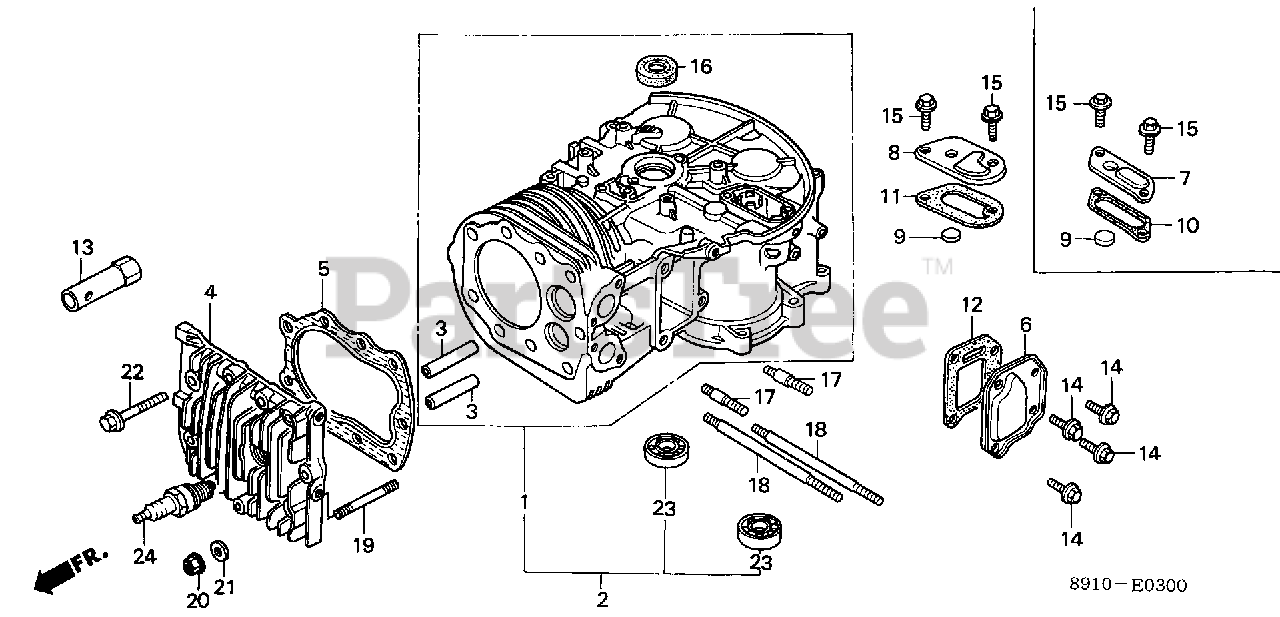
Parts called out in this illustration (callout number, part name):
3	GUIDE, VALVE
4	CYLINDER HEAD
5	GASKET, CYLINDER HEAD
6	COVER, TAPPET ROOM
8	CAP, BREATHER CHAMBER
9	VALVE, BREATHER
11	GASKET, BREATHER CAP
12	GASKET, TAPPET COVER
13	WRENCH, SPARK PLUG (NOT AVAILABLE)
14	BOLT, FLANGE (6X12) (CT200)
15	BOLT, FLANGE (6X16)
16	OIL SEAL (30X46X8)
17	BOLT, STUD (8X50)
17	BOLT, STUD (8X32)
19	BOLT, STUD (10X70)
20	NUT, FLANGE (10MM)
21	WASHER, PLAIN (10MM)
22	BOLT, FLANGE (10X55)
23	BEARING, RADIAL BALL (6203)
24	SPARK PLUG (BM6A) (NGK)
24	SPARK PLUG (BMR6A) (NGK)
24	SPARK PLUG (BPM6A-10) (NGK)
24	SPARK PLUG (BPMR6A-10) (NGK)
24	SPARK PLUG (W20M-U) (DENSO)
24	SPARK PLUG (W20MR-U) (DENSO)
24	SPARK PLUG (W20MP-U10) (DENSO)
24	SPARK PLUG (W20MPR-U10)
